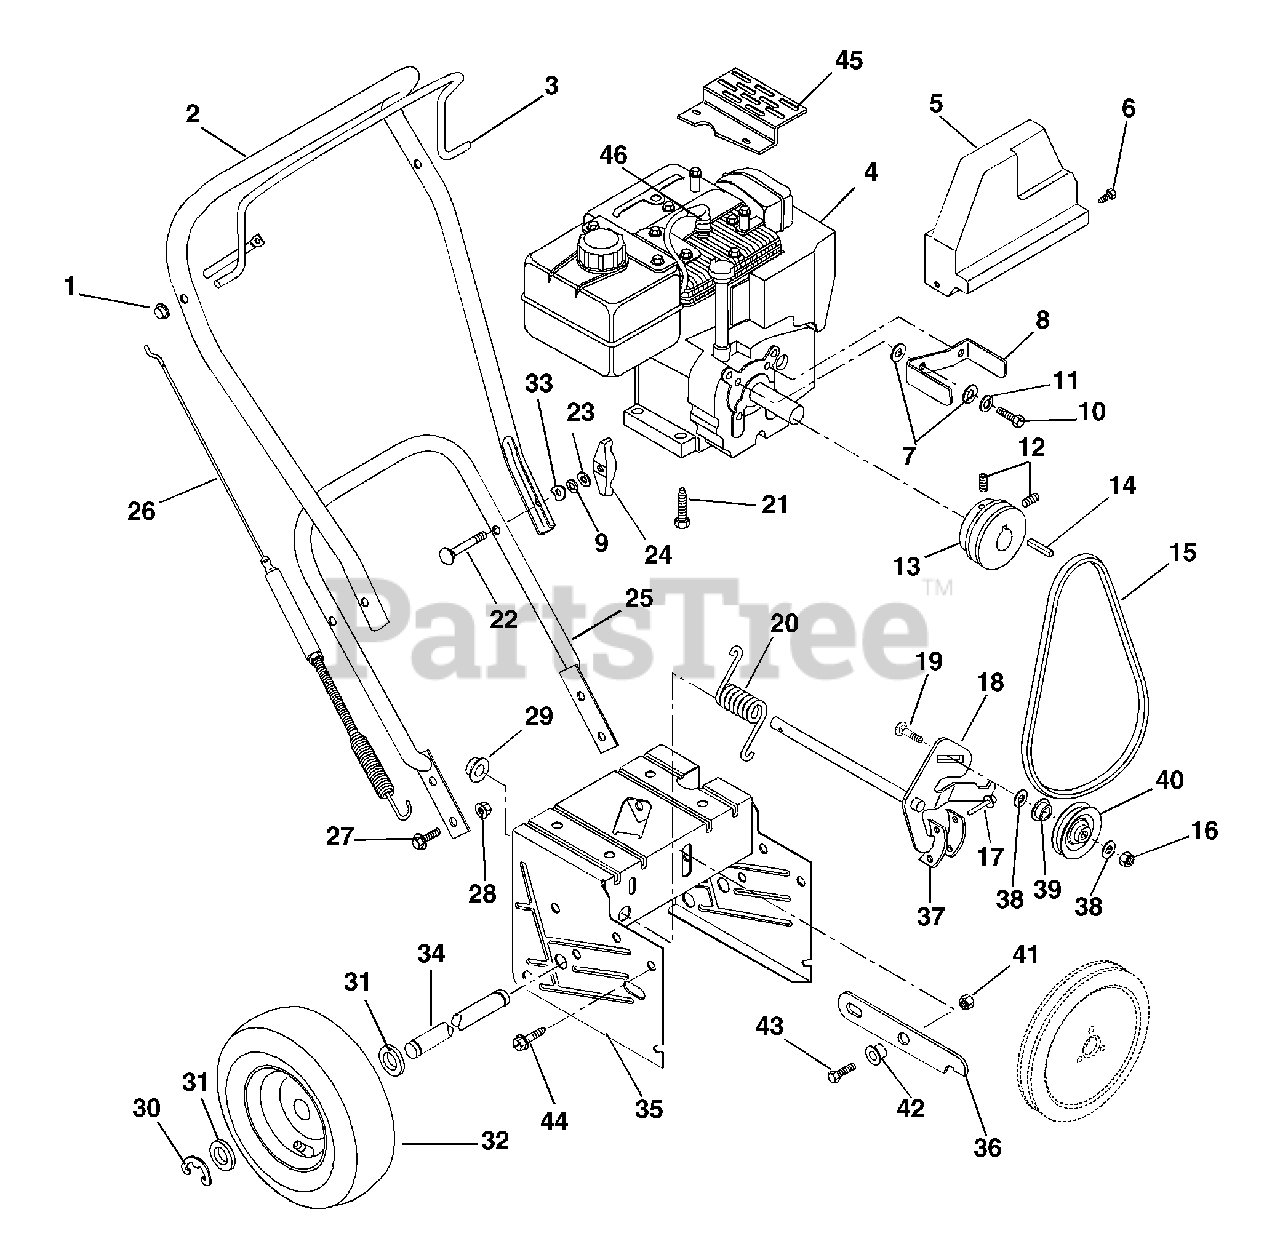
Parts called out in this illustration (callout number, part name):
1	NUT-PUSH .312 DIA. PAL
2	UPPER HANDLEBAR
4	ENGINE, 5HP LH TECUMSEH - 120V
5	COVER, BELT
6	@SCR-TAP .25-20X.37 HWH YWZ TR
7	WSHR-FL-STL .328X.87X.179 YWZC
8	BELT FINGER
9	WSHR-LK .312X.097 HVY YWZC
10	BLT-HEX .31-24X.75 YWZC GR5
11	WSHR-LK .313X.093 MED HICLR
12	SCR-SET .31-18X.38 SKHCUPDL
13	ENGINE SHEAVE
14	KEY-SQ .188X1.0X.188 SAE 8630
15	V-BELT, 4L-COGGED
16	@NUT-LK-CTR .31-18 YWZC
17	RVT-TBLR .187X.437 RH ST PL
18	BRAKE CLUTCH ARM W/LINING
19	@BLT-RDHDSQNK .31-18X1.50 G5YZ
20	SG-TORS .148X1.0X1.53
21	@SCR-TAP .38-16X1.00 HWH TR YZ
22	@BLT-RDHDSQNK .31-18X2.25 G5YZ
23	WSHR-FL-STL .328X.875X.062YWZC
24	KNOB - WING .312-18 UNC
25	HANDLEBAR, LOWER
26	CABLE, AUGER DRIVE
27	BLT SERHFWH .31-18X.62 GR5YWZC
28	@NUT-SPNLK-FLG .312-18 YWZC
29	CAP, .50 ROD YWZC
30	RG-RTNG-EXT .750X.050
31	WSHR-FL-STL.754X1.125X.062YWZC
33	WASHER,SADDLE-.320 X.937 X.062
35	FRAME, MAIN-WLDMT(AUGER DRIVE)
37	BRAKE LINING
38	@WSHR-FL-STL.38X.875X.083 YWZC
39	SPCR, BRG .315X.50X.688X.281
40	IDLER
41	@NUT-LK-CTR .25-20 YWZC
42	BSHG-FLG .265X.437X.250X.750
43	@BLT-HEX .25-20X.75 GR5 YWZC
44	@SCR-TAP .38-16X.50 HWH TR YWZ
45	SHIELD, MUFFLER
46	PLUG, SPARK
